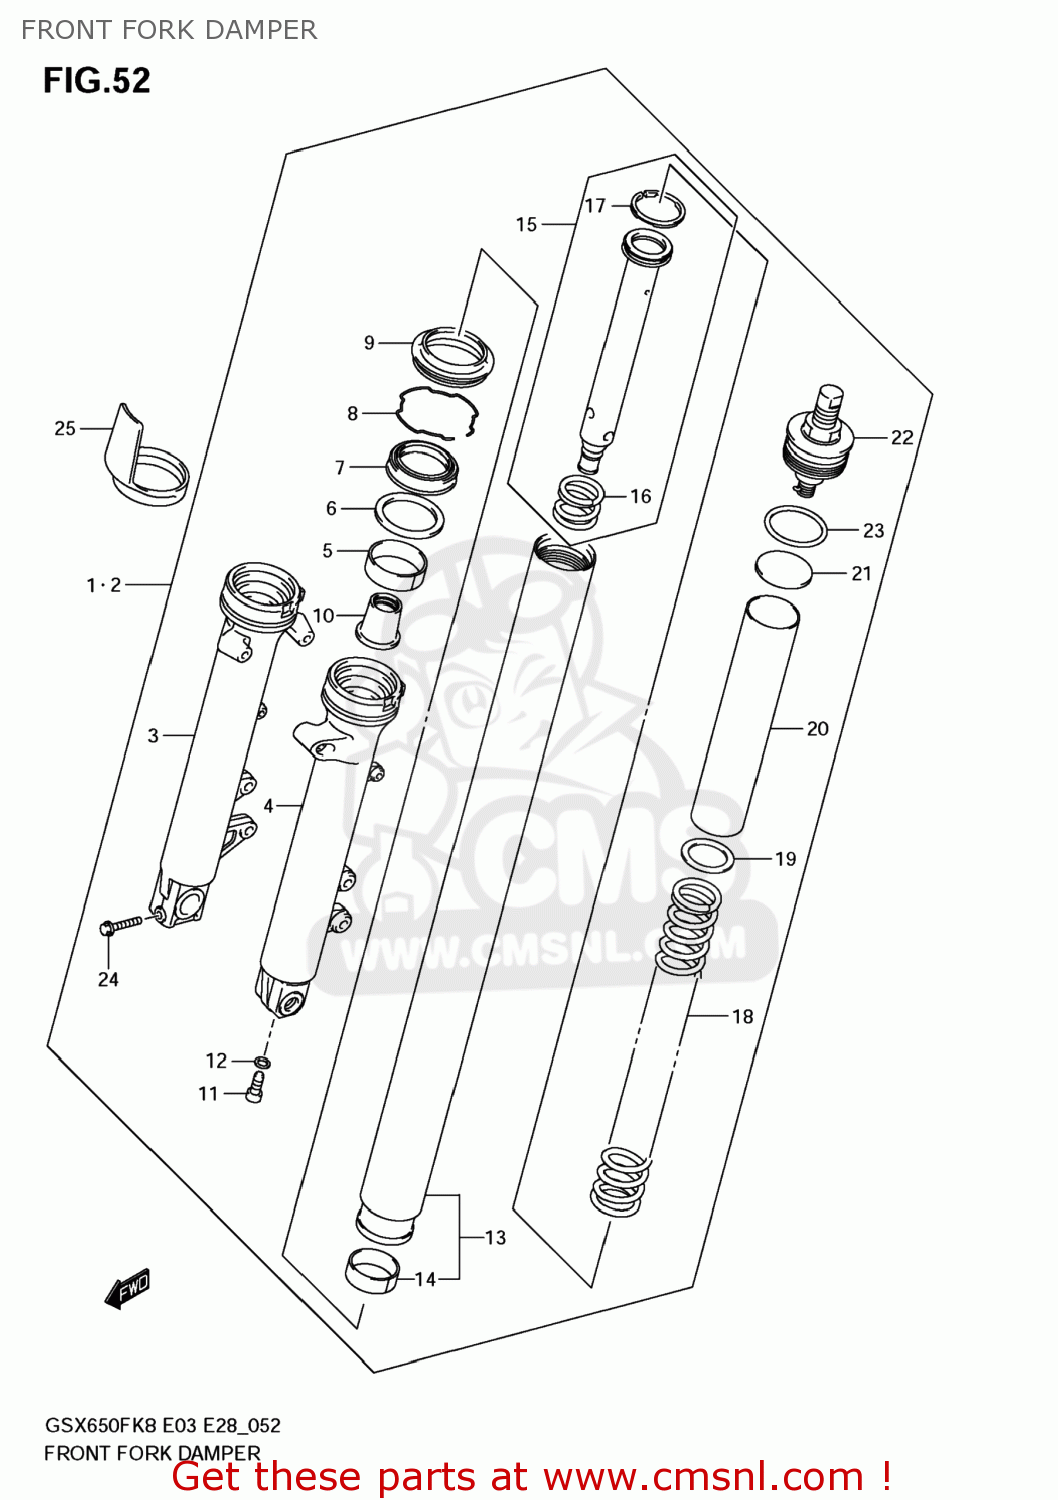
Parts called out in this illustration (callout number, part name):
1	DAMPER ASSY,FR FORK,R
2	DAMPER ASSY,FR FORK,L
3	TUBE,OUTER,R
4	TUBE,OUTER,L
5	METAL,SLIDE
6	WASHER,FORK OIL SEAL
7	SEAL,OIL
8	RING,OIL SEAL STOPPER
9	SEAL,DUST
10	PIECE,OIL LOCK
11	BOLT,FORK CYLINDER(10X25)
12	GASKET (NAS)
13	TUBE,INNER
14	PISTON
15	CYLINDER
16	SPRING,REBOUND
17	RING,PISTON
18	SPRING
19	WASHER
20	SPACER,SPRING
21	WASHER,FR FORK SPRING
22	CAP
23	O RING(D:3.5,ID:31.7)
24	BOLT
25	PROTECTOR
